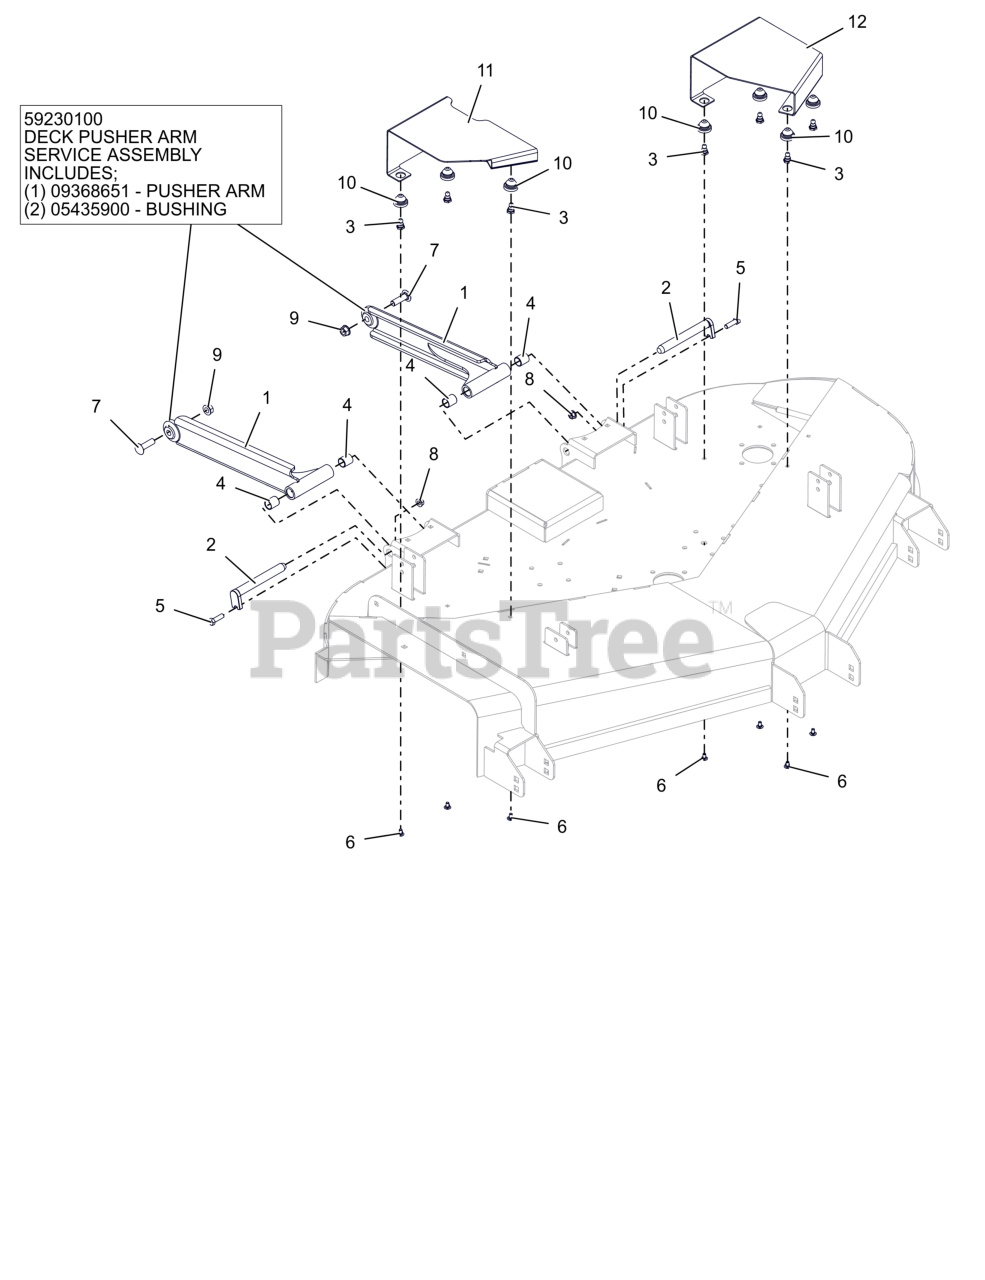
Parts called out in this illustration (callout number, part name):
1	WLDMT, DECK STABILIZER ARM (BLACK)
1	DECK PUSHER ARM SERVICE ASSEMBLY
1	BRG, .750 X .875 X 1.000
2	PIN, MOWER MTG
3	STUD, BALL FEMALE .250-20 THREAD
4	BRG, .750 X .875 X 1.000
5	BLT, HEX .38-16X1.25 G5 ZCC
6	BLT, RHSSN.25-20X.500 G5 ZCC
7	BTL,RHSSN .500-13 X 1.75 G5 ZCC
8	NUT-LK-CTR-FLG .375-16 GF ZCC
9	NUT-LK-CTR-FLG .500-13 GG ZCC
10	COUPLING, RUBBER PUSH-IN
11	COVER, RH BELT - TUNNEL DECK (RED)
12	GUARD- MACH1 LH BELT - RED
